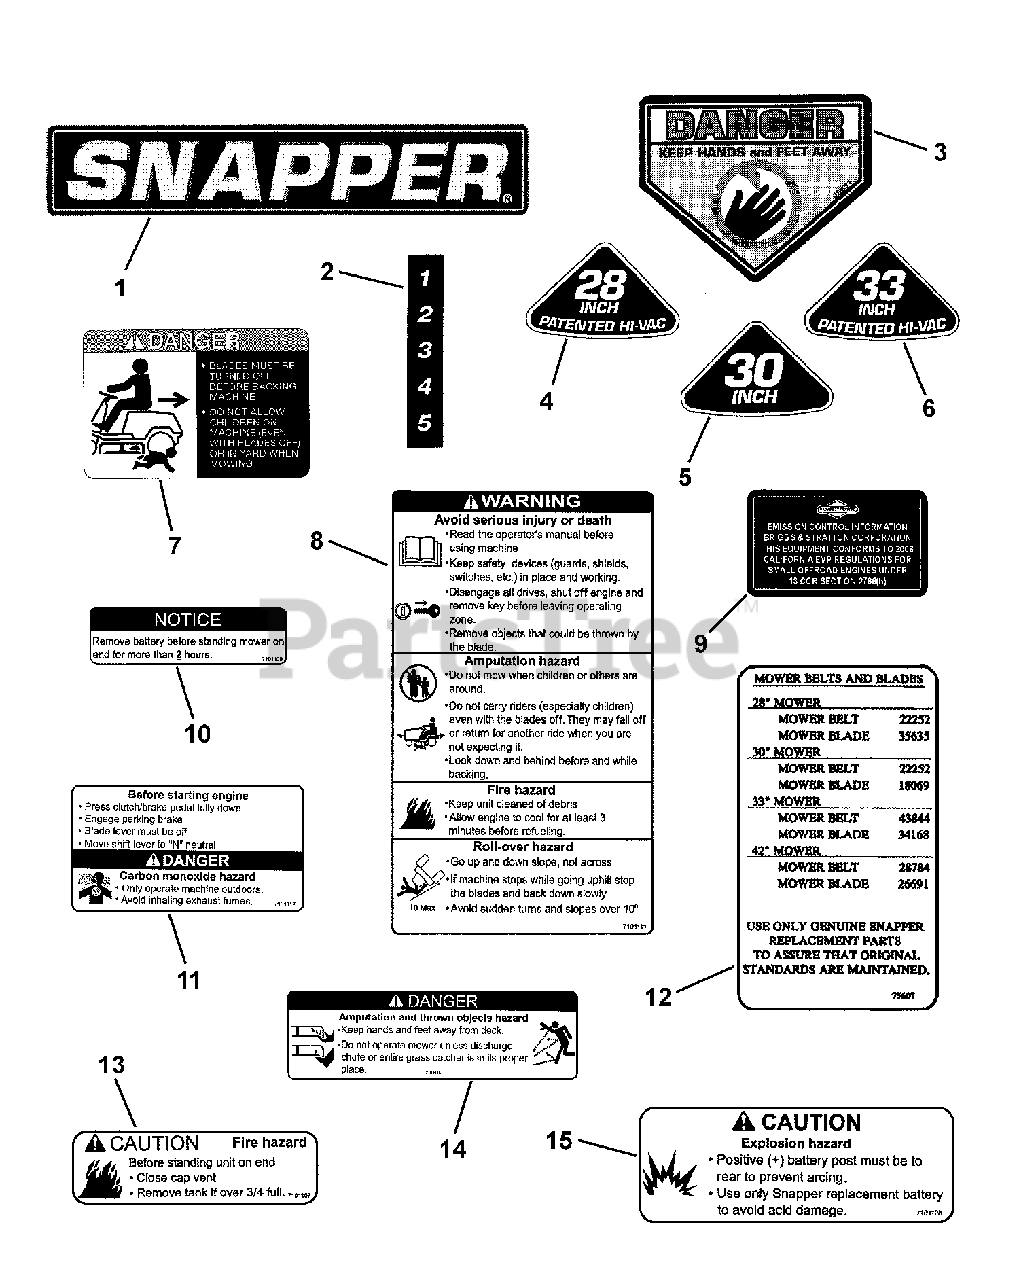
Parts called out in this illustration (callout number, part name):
1	DECAL, SNAPPER
2	DECAL, Height of Cut
3	DECAL, Danger (CPSC)
4	DECAL, 28 Inch (Hi-Vac)
5	DECAL, 30 Inch
6	DECAL, 33 Inch (Hi-Vac)
7	DECAL, No Mow in Reverse
8	DECAL, Warning, Safety Panel
9	LABEL, Emissions, Small Volume Exemption
10	DECAL, Remove Battery
11	DECAL, Danger, Safety Panel
12	DECAL, Service Parts, Domestic
13	DECAL, Caution, Fuel
14	DECAL, Danger, Deck
15	DECAL, Caution, Battery
